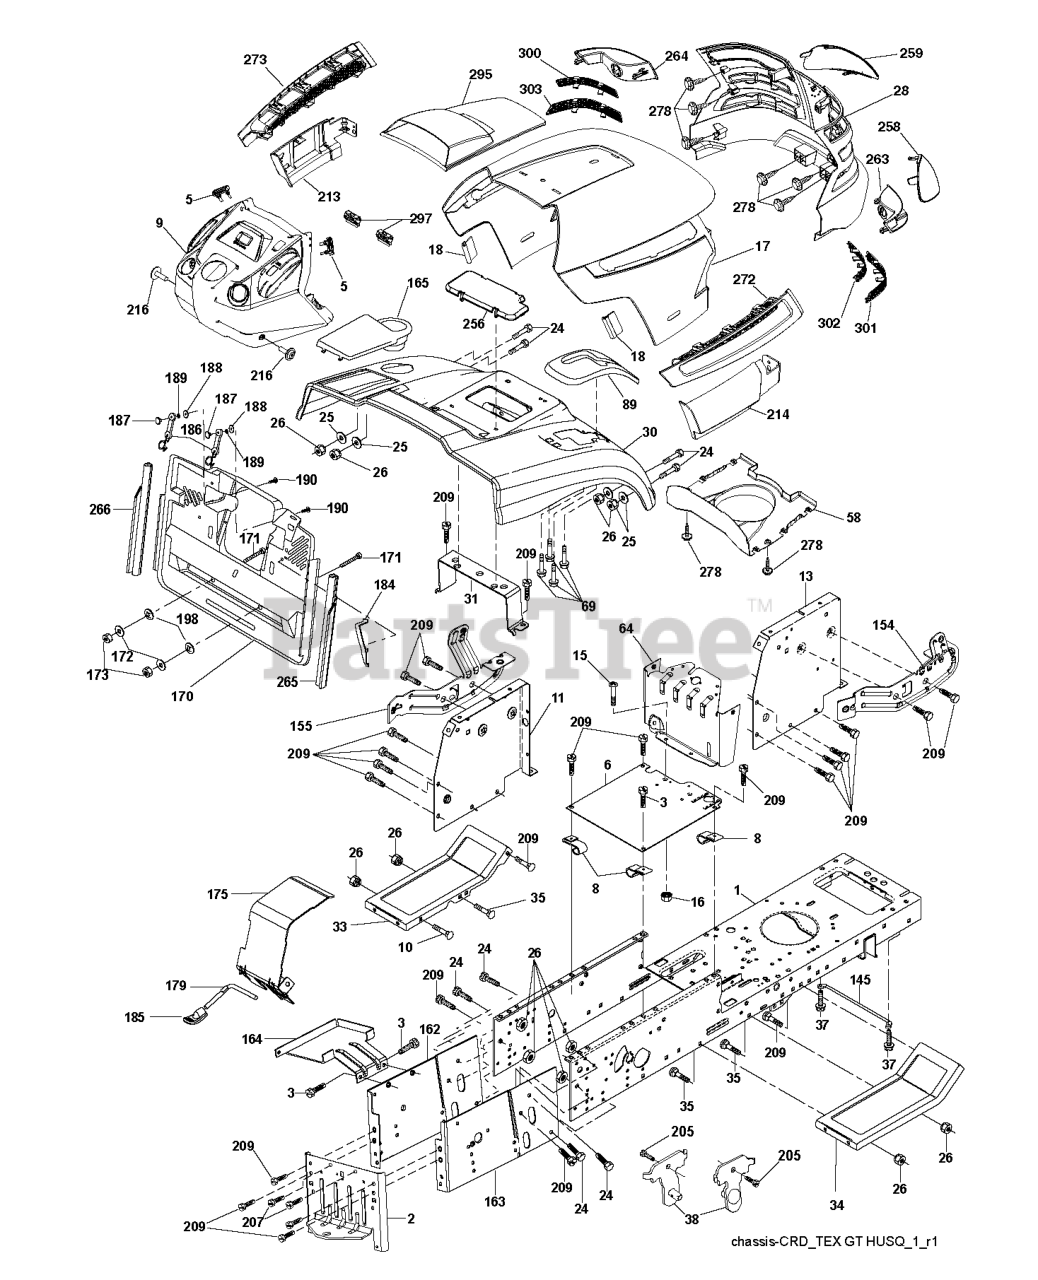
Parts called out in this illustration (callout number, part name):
2	DRAWBAR
3	SCREW 3/8-16X3/4
5	BUMPER DASH
6	PLATE
8	CLIP,INSULATOR
10	BOLT D
11	PANEL DASH LH
13	PANEL DASH RH
15	Screw, Machine, Truss Head 5/16-18 UNC x 3/4
16	NUT
17	HOOD
18	BUMPER.HOOD.TEX.HUSQVARNA
25	WASHER
26	NUT
28	GRILL.ASM.HUSQ.TG/CRD.W/TRIM
30	CONSOLE.CRD.AUTO.GRY
31	BRACKET SUPPORT FENDER
33	FOOTREST PNT LH
34	FOOTREST PNT RH
37	Screw 5/16-18 x 1/2 Hex, Self Tapping 5/16-18 x 1/2
38	BRACKET ASM PIVOT MOWER REAR
58	AIR.DUCT.HOOD.TEX.GT.HUSQ
69	SCREW.HI-LO.CONSOLE
89	CONSOLE.CRD.AUTO.GREY.2005
145	ROD.PIVOT.HOOD
162	BRACKET
163	BRACKET EXTEN CHASSIS RH CRD
165	RP.COVER.BATTERY.CRD.GREY
172	WASHER
175	DOOR TRAP
179	ROD PIVOT FBI
184	BRACKET.ACTUATOR.BAGGER.SRD
186	LATCH ASSY
187	WELDNUT
189	LOCKWASHER #10
190	SCREW
207	SCREW, 5/16-18 X 1/2
209	SCREW, 3/8-16X3/4
213	SKIRT.HOOD.SIDE.HUSQ.LH.GREY
214	SKIRT.HOOD.SIDE.HUSQ.RH.GREY
216	SCREW 14-20 X 5/8
256	COVER FENDER CRD
258	LENS.RH.TEX.GT.HUSQ.CL
259	LENS.LH.TEX.GT.HUSQ.CL
263	BEZEL.RH.TEX.GT.HUSQ
264	BEZEL.LH.TEX.GT.HUSQ
265	SEALING
266	SEALING
272	VENT.SIDE.HOOD.HUSQ.RH.GREY
273	VENT.SIDE.HOOD.HUSQ.LH.GRAY
278	SCREW.#10 X 0.750.BOS
295	HOOD VENT
297	CLIP.RETAINER.TINNER.
300	INSERT.HEX.GRILL.HUSQ.
301	INSERT.HEX.GRILL.HUSQ.GREY
302	INSERT.HEX.GRILL.HUSQ.
303	INSERT.HEX.GRILL.HUSQ.
